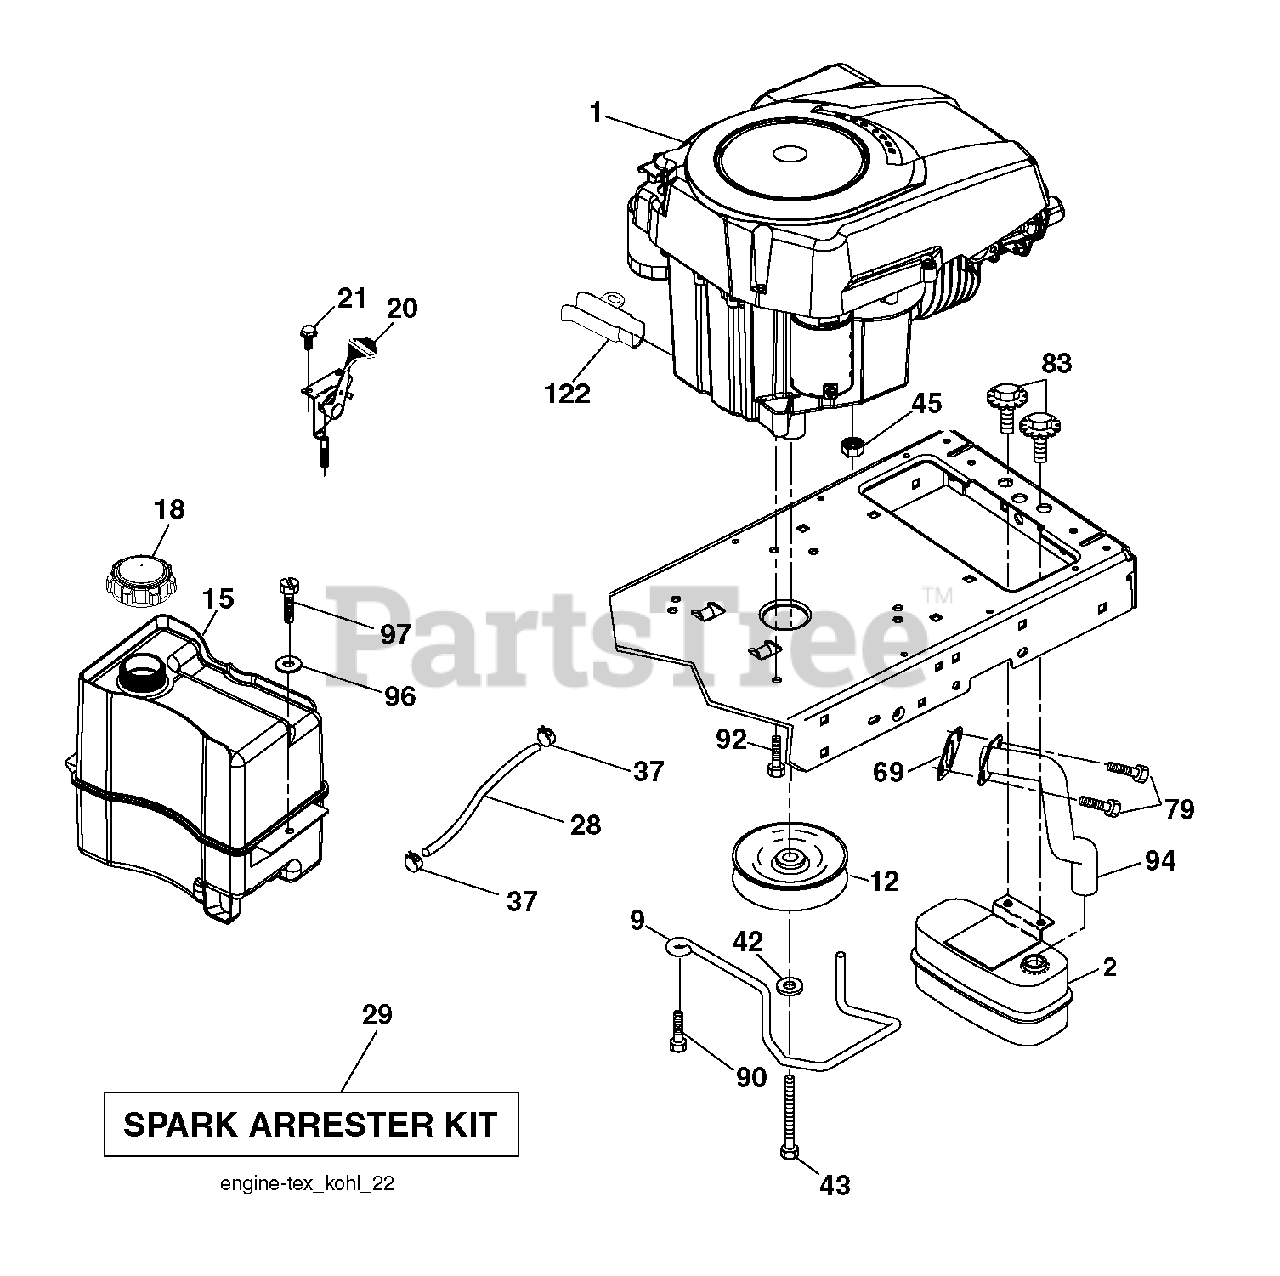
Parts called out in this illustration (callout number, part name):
1	Husqvarna TBD
2	MUFFLER.SINGLE.CYL.KOHL/B&S
9	KEEPER.BELT.ENGINE.4.2
12	PULLY ENGINE
15	RP TANK FUEL FRT 1.5 GAL
18	CAP ASM.FUEL.2.25"FR.
20	CONTROL.TH/CK.C.
21	SCREW.#10 X 0.750.BOS
28	LINE.FUEL.20
29	KIT.SPARK ARRESTOR 794945 B&S
37	HOSE CLAMP
42	LOCKWASHER
43	BOLT HEX 7/16-20X4-1/4"
45	NUT
69	GASKET.EXHAUST.KOHLER
79	SCREW.SOCKET HD.5/16-1
83	BOLT, 5/16-18 X 1 3/4
90	SCREW 3/8-16X1
92	SCREW 3/8-16X1
94	RP.TUBE.EXHAUST.KOHL.COURAGE
97	SCREW HEXWSHR 1/4-20X3/4
122	EXTENSION DRAIN OIL
